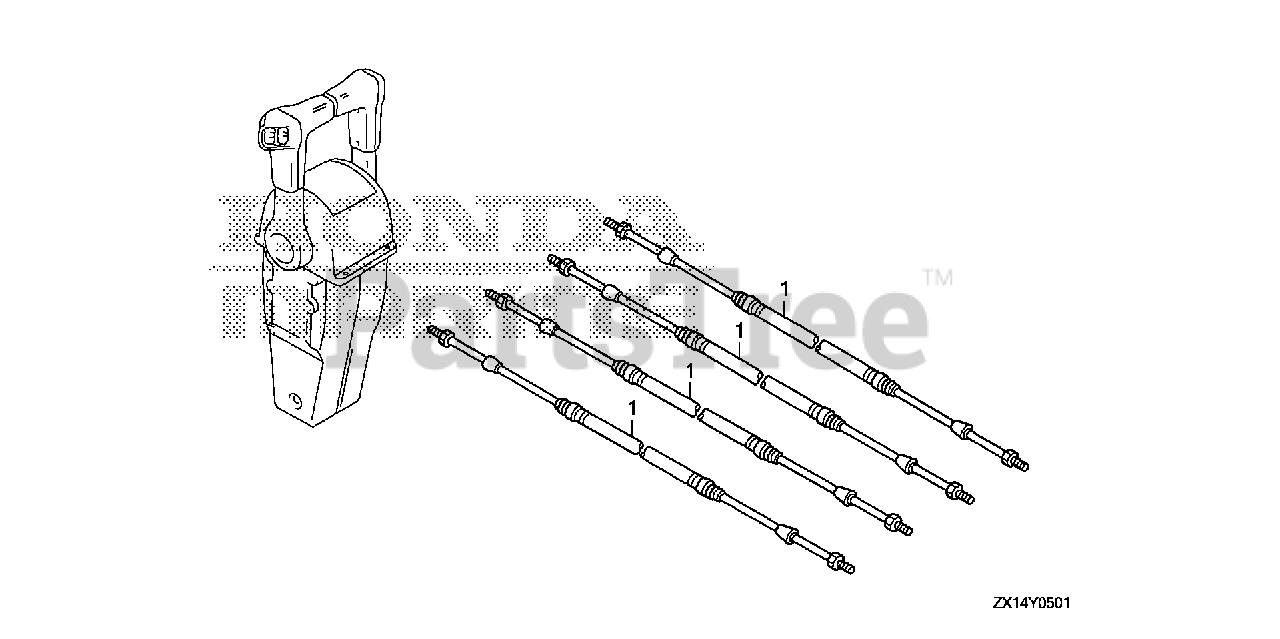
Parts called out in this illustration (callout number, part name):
1	CABLE ASSY., PUSH-PULL (33C-5FT)
1	CABLE ASSY., PUSH-PULL (33C-6FT)
1	CABLE ASSY., PUSH-PULL (33C-7FT)
1	CABLE ASSY., PUSH-PULL (33C-8FT)
1	CABLE ASSY., PUSH-PULL (33C-9FT)
1	CABLE ASSY., PUSH-PULL (33C-10FT)
1	CABLE ASSY., PUSH-PULL (33C-11FT)
1	CABLE ASSY., PUSH-PULL (33C-12FT)
1	CABLE ASSY., PUSH-PULL (33C-13FT)
1	CABLE ASSY., PUSH-PULL (33C-14FT)
1	CABLE ASSY., PUSH-PULL (33C-15FT)
1	CABLE ASSY., PUSH-PULL (33C-16FT)
1	CABLE ASSY., PUSH-PULL (33C-17FT)
1	CABLE ASSY., PUSH-PULL (33C-18FT)
1	CABLE ASSY., PUSH-PULL (33C-19FT)
1	CABLE ASSY., PUSH-PULL (33C-20FT)
1	CABLE ASSY., PUSH-PULL (33C-21FT)
1	CABLE ASSY., PUSH-PULL (33C-22FT)
1	CABLE ASSY., PUSH-PULL (33C-23FT)
1	CABLE ASSY., PUSH-PULL (33C-24FT)
1	CABLE ASSY., PUSH-PULL (33C-25FT)
1	CABLE ASSY., PUSH-PULL (33C-26FT)
1	CABLE ASSY., PUSH-PULL (33C-27FT)
1	CABLE ASSY., PUSH-PULL (33C-28FT)
1	CABLE ASSY., PUSH-PULL (33C-29FT)
1	CABLE ASSY., PUSH-PULL (33C-30FT)
1	CABLE ASSY., PUSH-PULL (33C-31FT)
1	CABLE ASSY., PUSH-PULL (33C-32FT)
